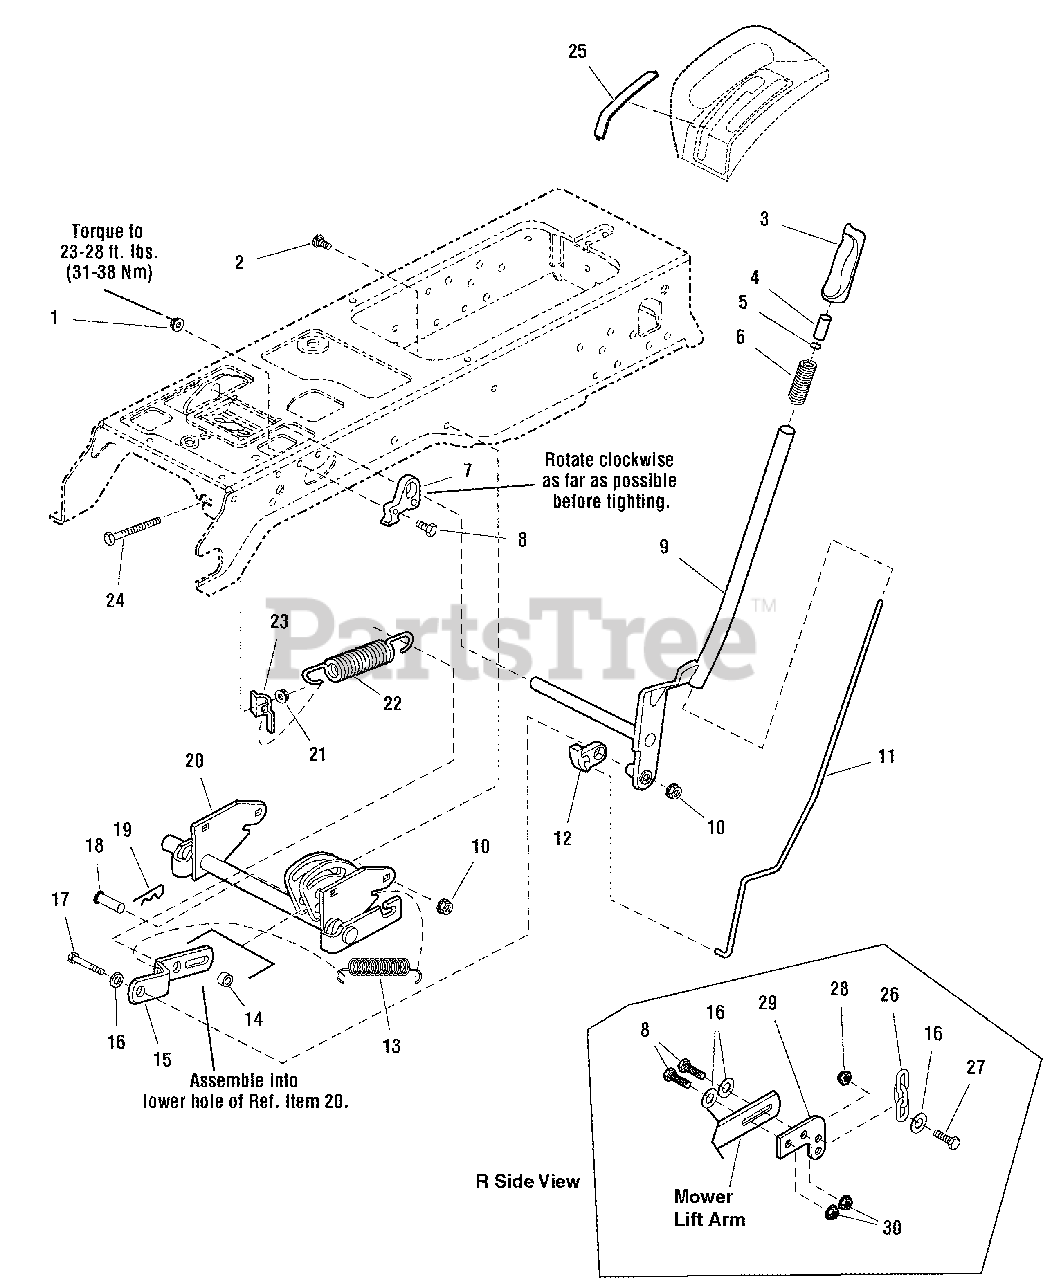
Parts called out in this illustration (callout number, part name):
1	NUT, Flange, 5/16-18
2	CARRIAGE BOLT, 5/16-18 x 3/4
3	GRIP, Lift Lever
4	BUTTON, Red Nylon, for 1/4 Rod
5	NUT, Push Pal 1/4 Diameter Thread
6	SPRING, Compression, Lift Lever
7	QUADRANT, Lift, Powdered Metal
8	CAPSCREW, 5/16-18 x 1, G8
9	LEVER ASSEMBLY, Lift
10	NUT, Hex, 5/16-18
12	LOCK, Lift, Powdered Metal
13	SPRING, Extension
14	SPACER, 1/2 x 3/4 x 23/32
15	BAR, Lift Link
16	WASHER, 5/16, Black
17	CAPSCREW, Hex Head, 5/16-18 x 2-1/4
18	PIN, Flat Head, 1/2 x 2-1/8
19	CLIP, Hair Pin, 2-9/16 Long
20	SHAFT ASSEMBLY, Lift
21	NUT, Speed, 5/16-18, Lug
22	SPRING, Extension
23	RETAINER, Spring Flat
24	CAPSCREW, Hex Head, 5/16-18 x 4-1/2
25	COVER, Hand Control
26	CHAIN, 3-Link
27	CAPSCREW, Hex Head, 5/16-18 x 1-1/2
28	NUT, Nylock, 5/16-18
29	ARM, Lift, Duel, Mower
30	NUT, Whizlock, 5/16-18
31	CAPSCREW, 5/16 x 1 1/2
